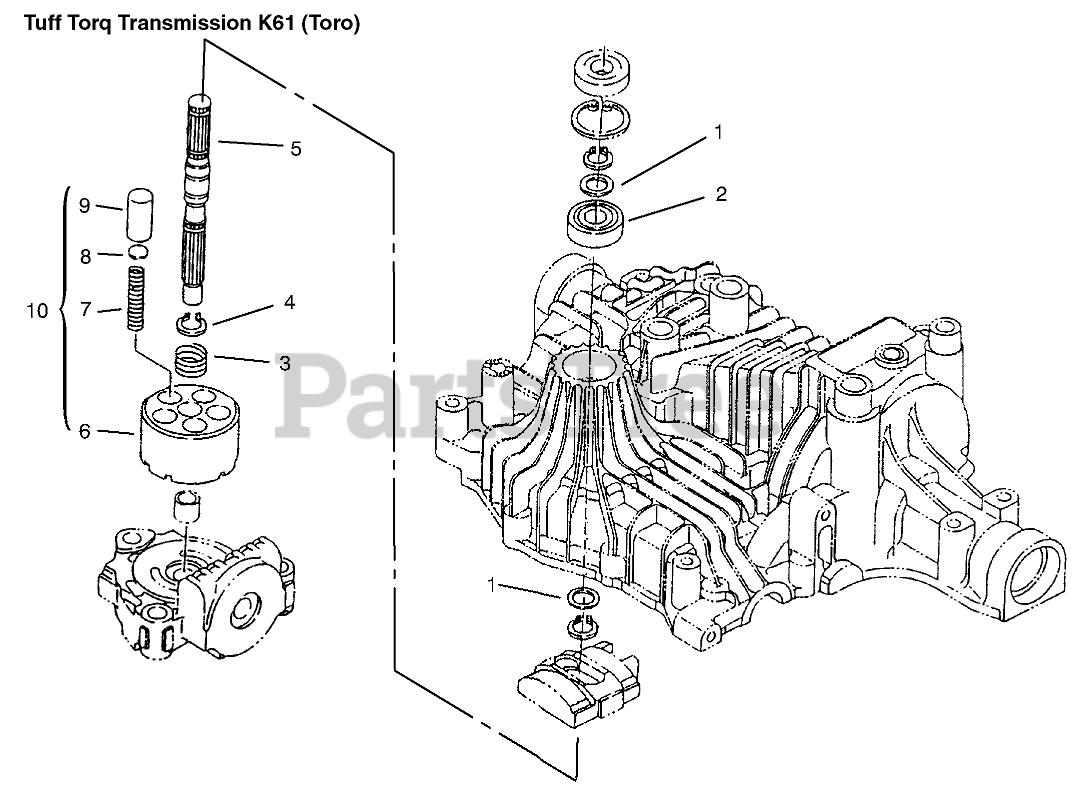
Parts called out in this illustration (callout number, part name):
1	WASHER
2	BEARING-BALL
3	SPRING
4	RING-SNAP
5	SHAFT - PUMP
6	Block-Cylinder
8	Washer
10	ASM - CYCLINDER INC 6-9
